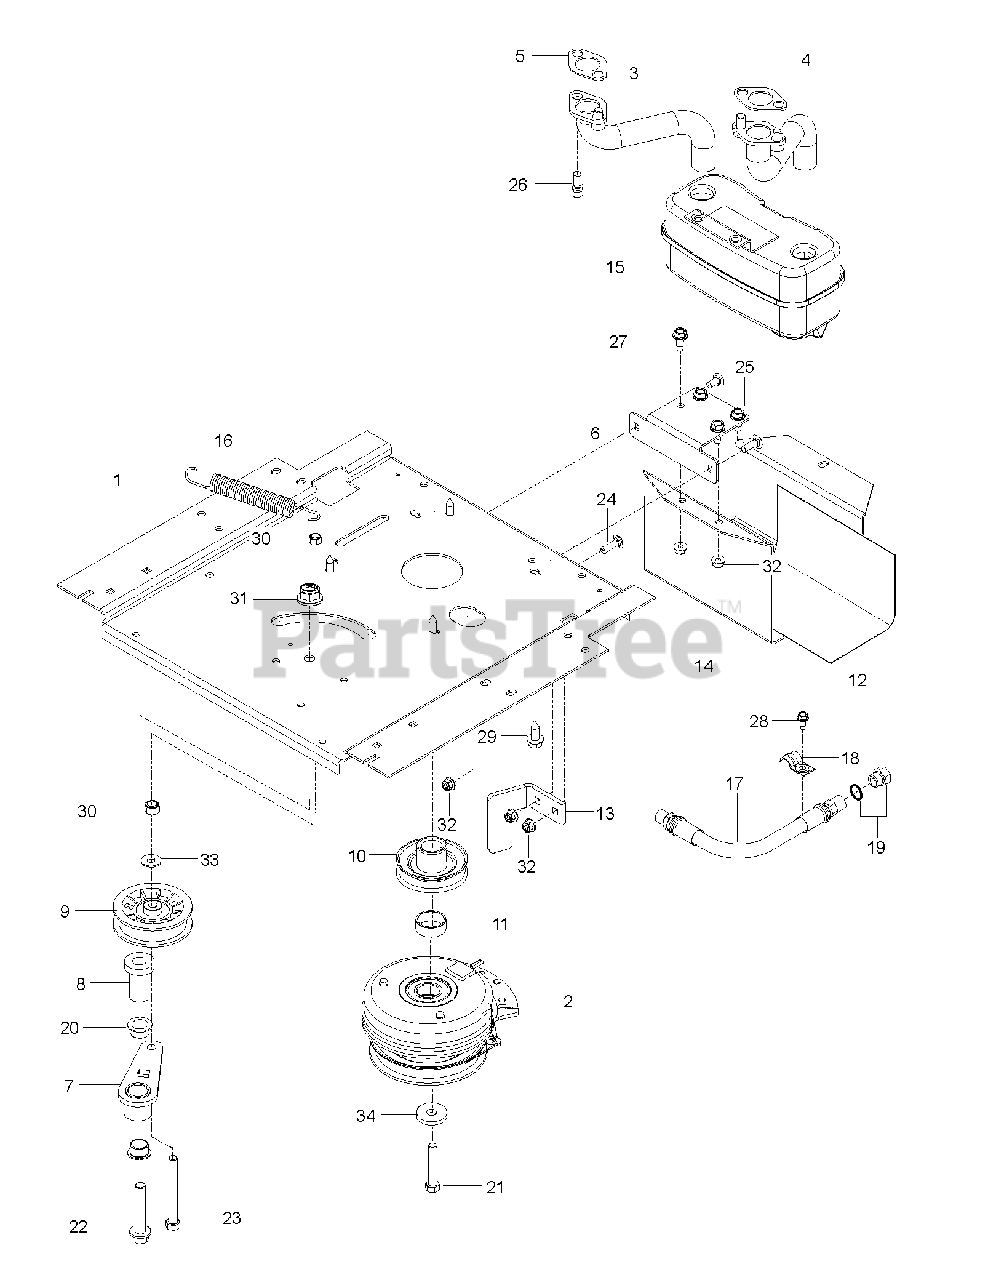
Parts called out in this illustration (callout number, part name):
1	PLATE.ENGINE.PNT.23"FRAME.EDIP
2	CLUTCH.105.FT-LBS
3	PIPE.EXHAUST.RH.CV18/20
4	PIPE.EXHAUST.LH.CV18/20
5	GASKET
6	BRACKET MUFFLER MS431BLK
7	ARM IDLER
8	SPINDLE.IDLER
9	PULLEY, IDLER RAKE & ZTR
10	PULLEY.ENGINE
11	SPACER.SPACER.625 W/OGURA.LCC
12	HEAT SHIELD
13	CLUTCH.STOP.OGURA LCC.BLACK
14	GUARD.MUFFLER.WO.TOW.HITCHX431
15	MUFFLER ASM TWIN
16	SPRING, DECK DRIVE
17	HOSE.ASSEMBLY.OIL.DRAIN
19	PLUG OIL DRAIN
20	BEARING.FLANGED.PLASTIC.3/4ID
21	CLUTCH BOLT7/16-20X3.5 GR524HR
22	BOLT.FLANGE.1/2-13 X 2.75.GRD5
23	HCS 3/8-16X3-1/2 TAPBLT GR5 ZD
24	RHSNB 5/16C X 1
25	BOLT 5/16C X 3/4" CARRIAGE
26	SCREW.SOCKET HD.5/16-1
27	BOLT
28	SCR 1/4-20X5/8 HEX SELF TAP ZD
29	SCREW 3/8-16X1
30	NUT 3/8-16 NYLOC
31	NUT, 1/2-13 HEX FLG NYLOC ZD
32	5/16-18 NYLOC FLANGE NUT
33	WASHER
